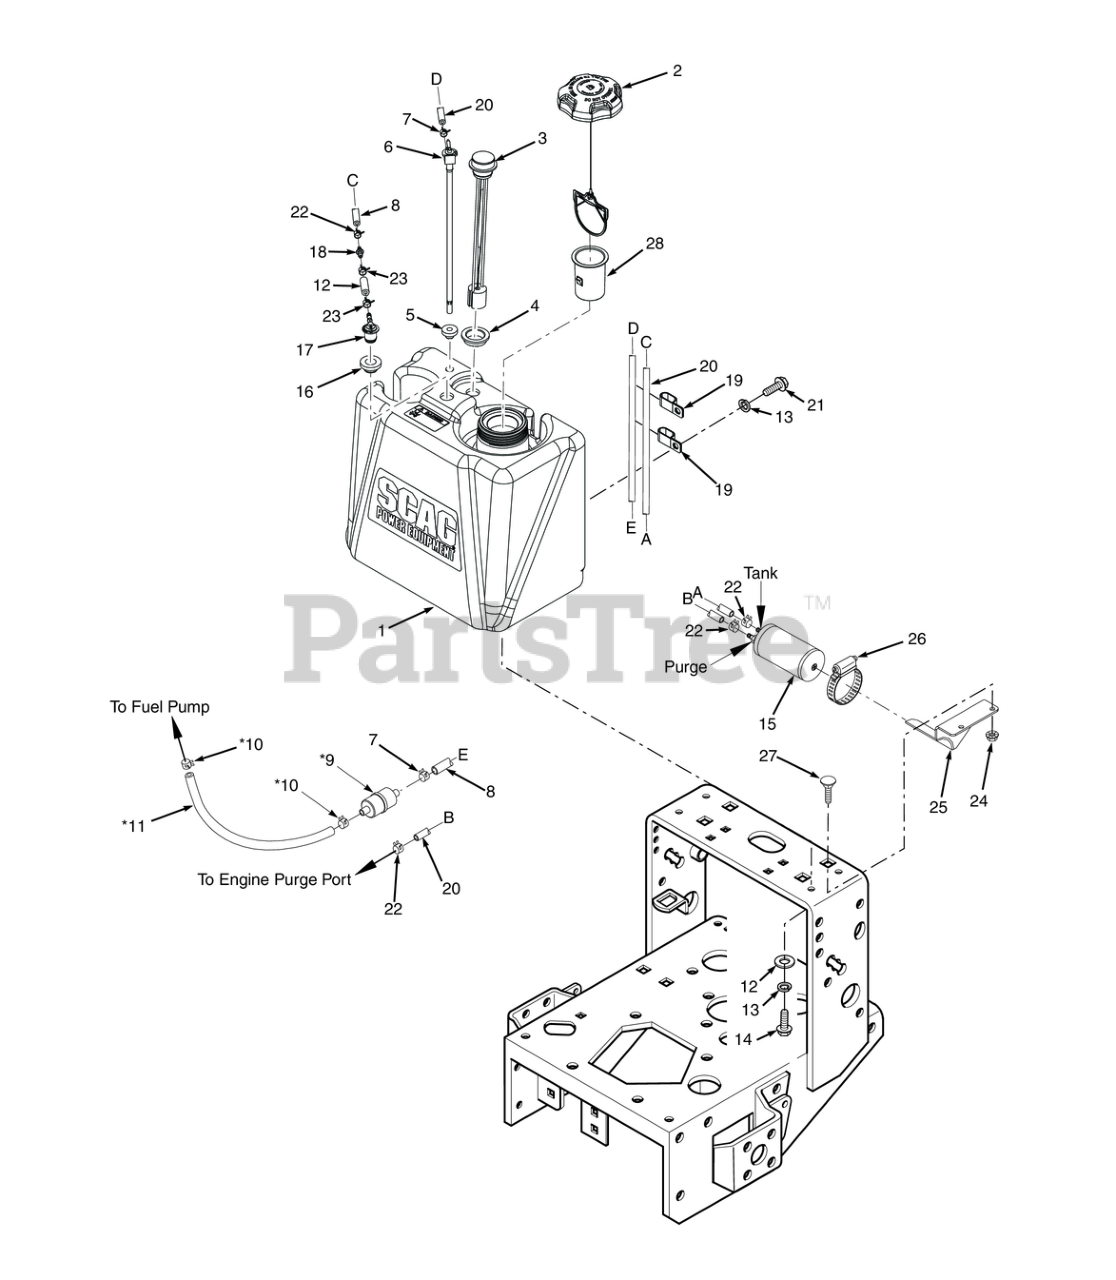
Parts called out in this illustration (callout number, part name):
1	Fuel Tank Assembly (incl. #2, 3, 5, 6, 17, 18)
2	Fuel Cap w/ Tether (E.P.A.)
2	Fuel Cap w/Tethered - California Models Only
3	Fuel Gauge Assembly
4	Grommet, Fuel Gauge
5	Bushing, 0.56" Dia. Viton
6	Valve, Fuel Shutoff w/Screen
7	Clamp, Fuel Hose 1/4" Hose I.D.
8	Fuel Hose, 1/4" I.D. Non-Perm (791DFI Fuel Return) - Order by Inch
9	Fuel Filter
10	Clamp, Fuel Hose
11	Fuel Hose
12	Hose, 1/4" Vapor Recovery (order by inch)
13	Lockwasher, 5/16 (.317 x .586 x .078) Helical Spring
14	Bolt, Heax Head 5/16-18 x 1" (48V / 52V)
15	Carbon Canister - SVR-36A / SVR-48V
16	Grommet, Viton,
17	Remote Vent, No Valve
18	Mender, 1/4 x 3/16 w/0.02 Hole
19	Clamp, Double Cable 5/8" ID.
20	Hose, Vapor Recovery 3/16" (order by inch)
21	BOLT, SERRATED FLANGE HEX HEAD 5/16-18 X 3/4"
22	Clamp, Vapor Recovery Hose 3/16"
23	CLAMP, FUEL HOSE(KAWASAKI ONLY)
24	Nut, Serrated Flange 5/16-18 (Right Front Engine Mounting, Briggs and Kohler Only)
25	Bracket, Canister Mounting
26	Clamp, 3-1/2" Max. Dia.
27	Bolt, Carriage 5/16-18x1" (large frame units only)
28	Tube, Fuel Tank Insert - 4"
